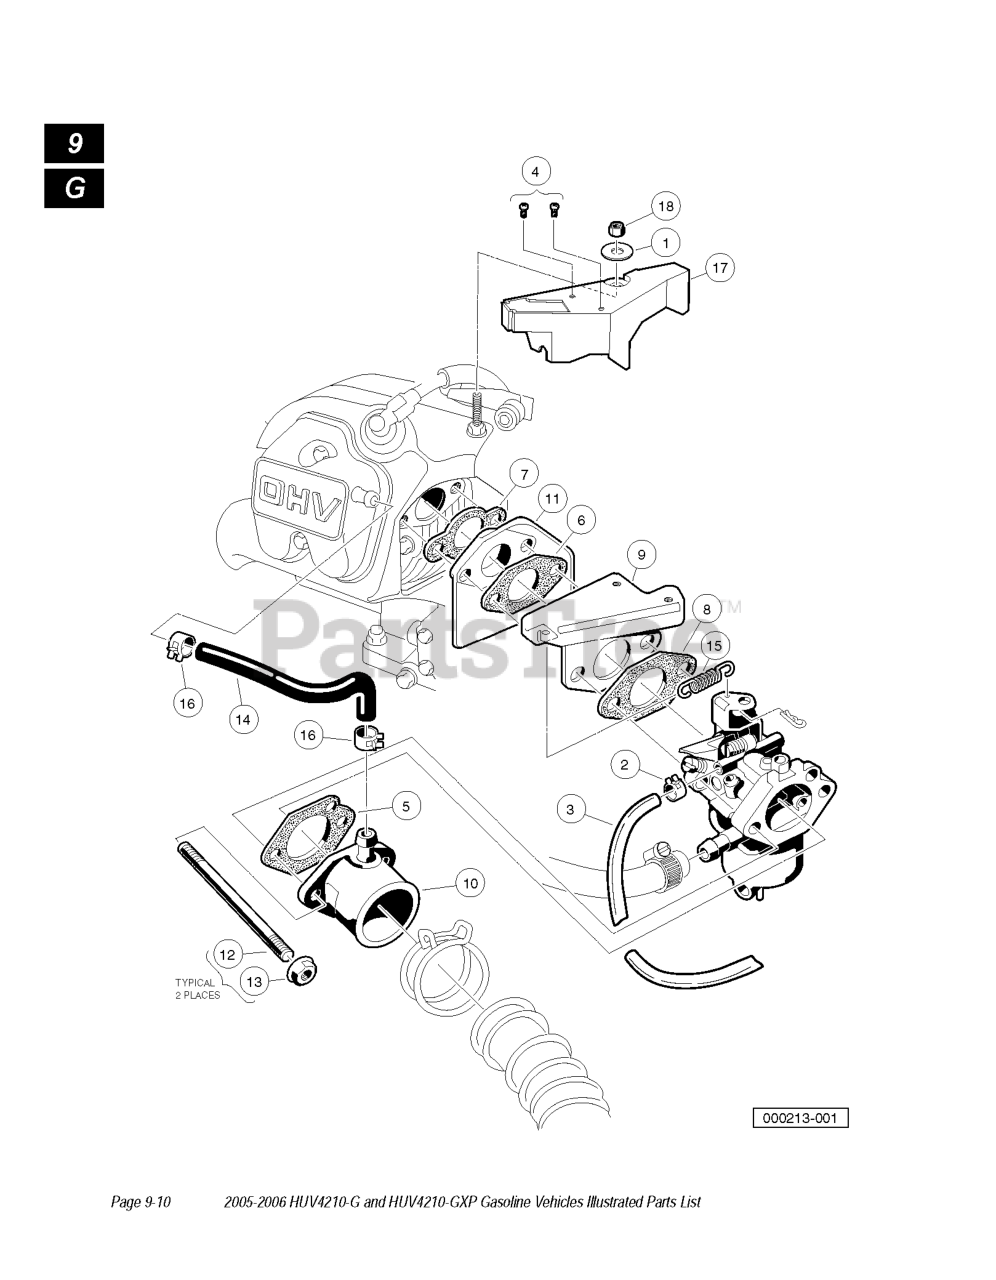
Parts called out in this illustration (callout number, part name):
1	WASHER, 5/16 FLAT
3	FUEL LINE
4	SCREW, PAN HD TX TAPTITE 6-32
5	GASKET, CARB TO INTAKE MANIFOL
6	GASKET, INSULATOR TO SPRG BRKT
7	GASKET, ENGINE TO INSULATOR
8	GASKET, SPRG BRKT TO CARB OHV
9	BRACKET, THROTTLE SPRG RETURN
10	PIPE, INTAKE MANIFOLD
11	INSULATOR, CARBURETOR
12	STUD, M6-1.00 2-ENDED
14	TUBE, CRANKCASE VENT
15	SPRING, THROTTLE RETURN
17	SHIELD, GOVERNOR
18	LOCKNUT, M6-1.00 NYLON INSERT
